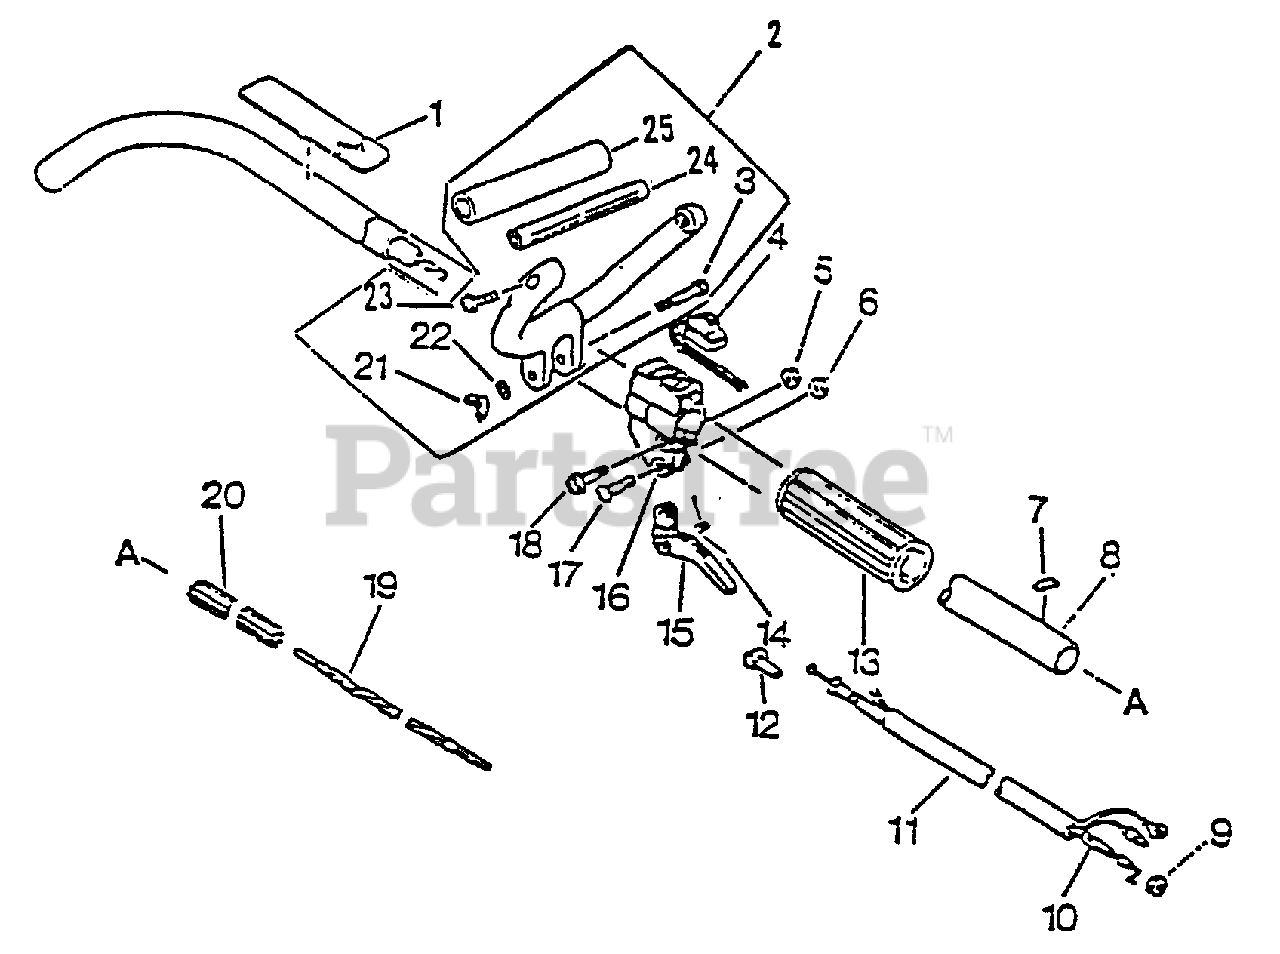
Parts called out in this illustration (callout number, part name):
1	LABEL - CAUTION
2	HANDLE
3	BOLT - 6X40
4	IGNITION SWITCH ASSY
6	LOCKNUT - 5
7	LABEL - ALIGNMENT
8	PIPE, MAIN
10	CABLE, THROTTLE
11	TUBE - VINYL
12	GUIDE, CABLE
13	GRIP, HANDLE
14	SPRING, TRIGGER
15	TRIGGER, THROTTLE
16	BRACKET, THROTTLE CONTROL
17	SCREW - 5X30
18	SCREW - 5X28
19	DRIVESHAFT - FLEXIBLE
20	LINER - FLEXIBLE
21	WINGNUT - 6
22	WASHER - 6
23	SCREW - 5X30
24	HANDLE - FRONT
25	GRIP, HANDLE
